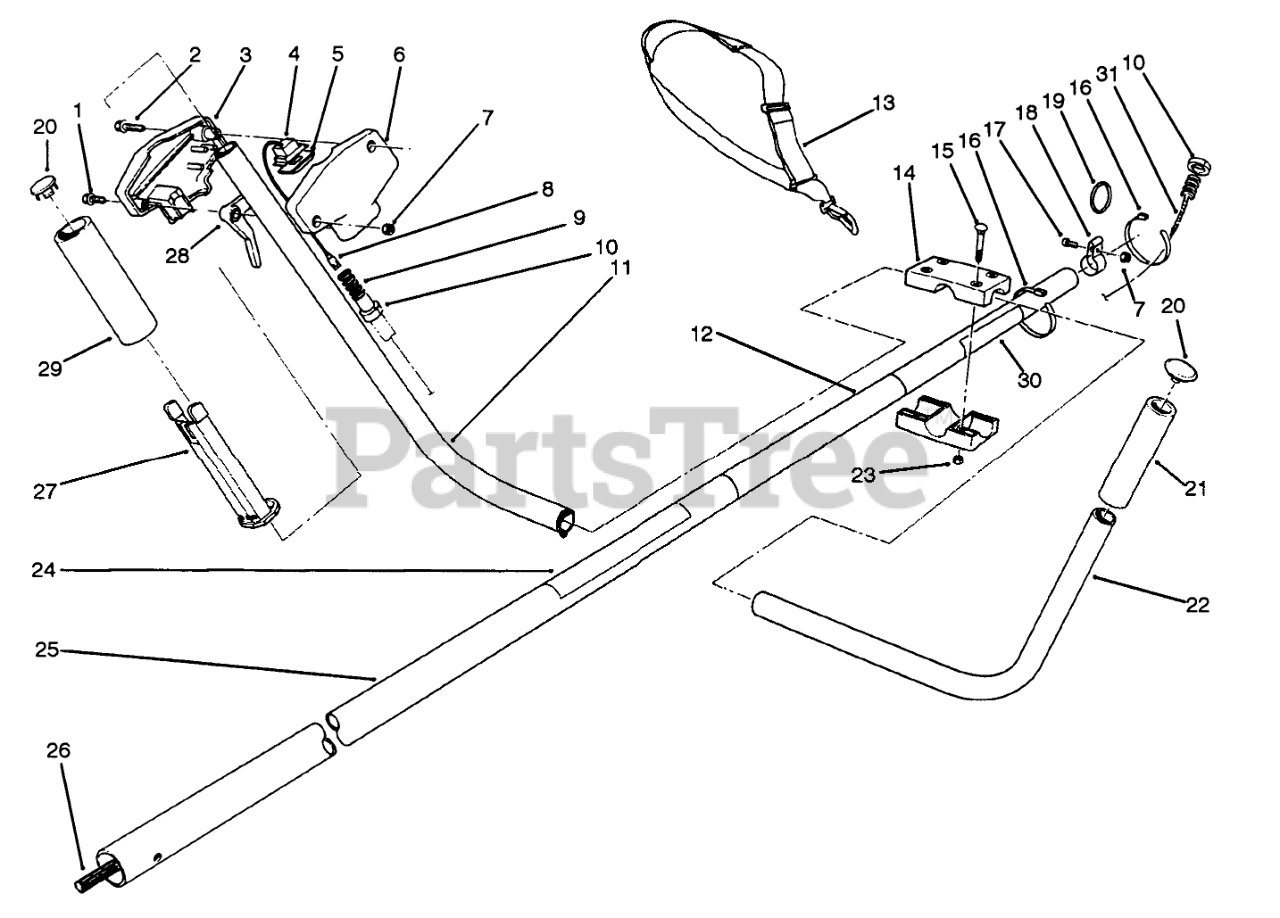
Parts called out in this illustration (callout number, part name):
1	SCREW-SHOULDER
3	RH HOUSING
4	SWITCH
5	SWITCH COVER
6	LH HOUSING
7	NUT-LOCK, NI
8	WIRE ASM
9	Cover-Cable
10	RING FITTING
11	RH HANDLE
12	DECAL - WARNING
13	Harness-Shoulder
14	CLAMP
15	SCREW-CARR
16	TIE-CABLE
17	SCREW-SRH
18	HARNESS CLAMP
19	RING-HARNESS
20	TUBE CLOSURE
21	FOAM GRIP
22	LH HANDLE
23	NUT-LOCK, NI
24	Decal-TC 5010
25	TUBE ASM
26	SPLINE SHAFT
27	TROUGH
28	THROTTLE LEVER
29	GRIP-RUBBER
30	DECAL-INSTRUCTION
31	THROTTLE CABLE
